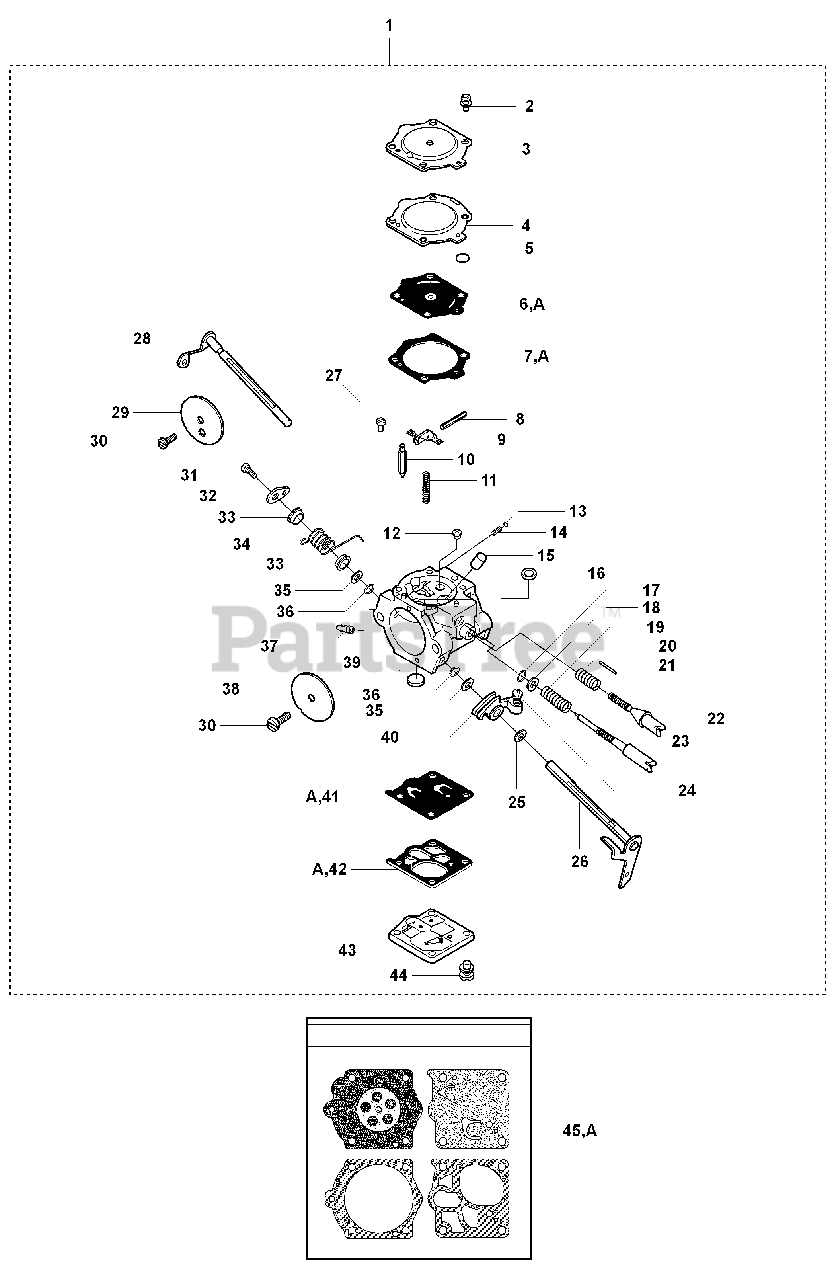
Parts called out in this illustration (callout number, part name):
1	CARBURETTOR
3	COVER-METERING DIAPH
6	DIAPHRAGM ASSY METER
7	GASKET-METERING DIAP
8	PIN-METERING LEVER
9	LEVER-METERING
10	VALVE INLET NEEDLE
11	SPRING-METER.LEVER
13	BALL-CHOKE FRICTION
14	SPRING-CHOKE FRICT.
15	NOZZLE ASSY
16	PLUG-WELCH
19	SPRING-NEEDLE
21	PIN THROTTLE STOP
22	SCREW IDLE SPEED
23	NEEDLE IDLE SPEED
26	SHAFT ASS'Y THROTTLE
27	SCREW-LEVER PIN
28	SHAFT ASS'Y
29	VALVE CHOKE
30	SCREW-VALVE
31	SCREW PAN HD
32	LEVER THROTTLE
33	BUSHING-THROTT.SPR.
34	SPRING THROTT RETURN
36	SEAL-THROTTLE SHAFT
37	FITTING FUEL INLET
38	VALVE THROTTLE
39	SCREEN-INLET
40	LEVER THROTTLE INNER
41	DIAPHRAGM-PUMP
42	GASKET-PUMP
43	COVER-PUMP
44	SCREW-PUMP COVER
45	GASKET KIT
